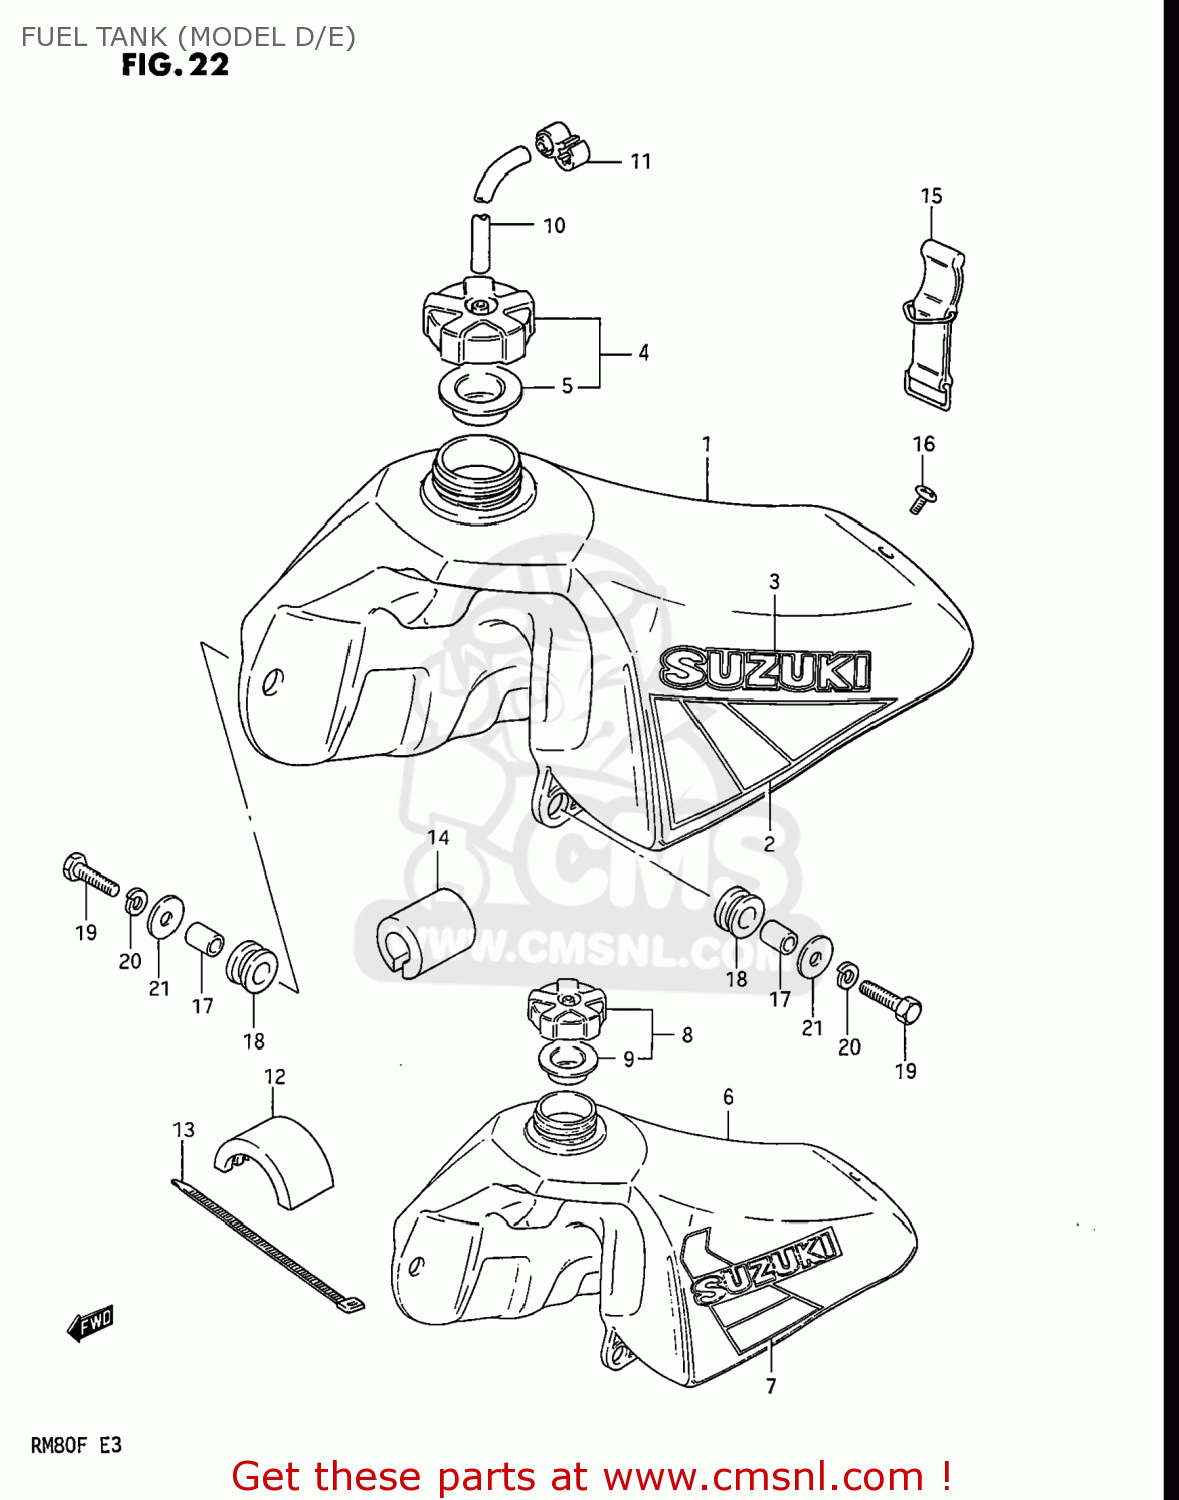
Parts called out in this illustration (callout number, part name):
1	TANK ASSEMBLY,FUEL
2	TAPE SET,FUEL TANK
3	EMBLEM,REAR FENDER
4	CAP SET,FUEL TANK
5	GASKET,FUEL TANK CAP (NAS)
6	TANK ASSEMBLY,FUEL
7	TAPE SET,FUEL TANK
8	CAP SET,FUEL TANK
9	GASKET,FUEL TANK CAP (NAS)
10	HOSE
11	CLAMP,FUEL TANK BREATHER HOSE
12	CUSHION,FUEL TANK UPR FR
13	CLAMP
14	CUSHION,FUEL TANK UPR RR
15	BAND
16	SCREW (6X15)
17	SPACER (6.8X10X11.5)
18	CUSHION
19	BOLT
20	LOCK WASHER
21	WASHER (6.5X24X1.6)
